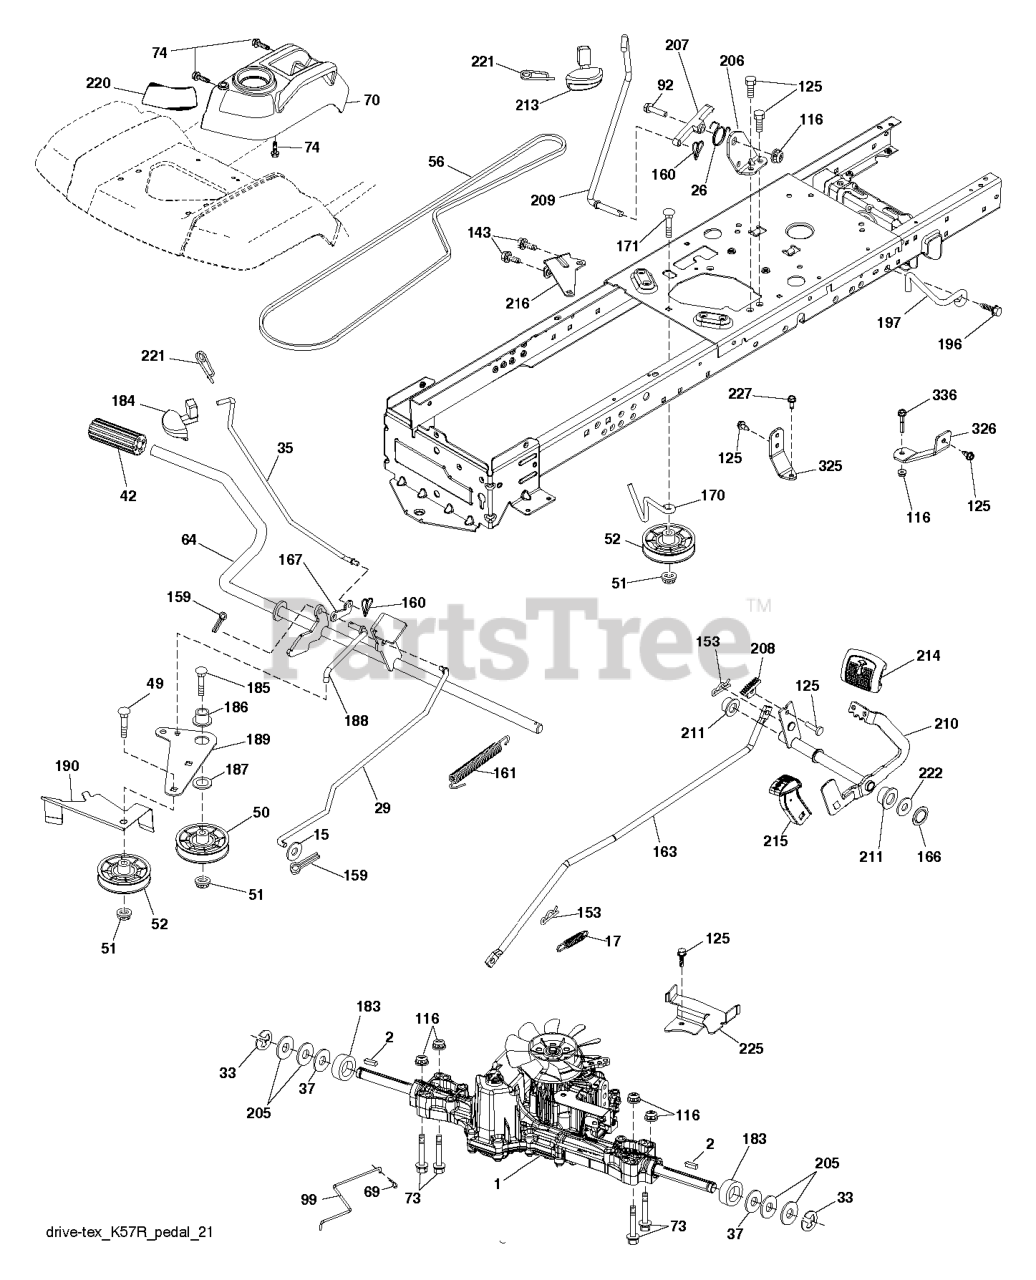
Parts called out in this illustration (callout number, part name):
2	SQUARE KEY
15	WASHER
17	SPRING.BRAKE.K46.GREEN
26	SPRING.RETURN.CRUISE
29	ROD.BRAKE.K46
35	ROD .BRAKE. PARKING. GT. HUSQ.
37	WASHER.HARDENED
42	PEDAL COVER T
50	IDLER.FLAT.910.OFFSET
51	NUT LOCK FLG 3/8-16 UNC
52	IDLER.V-GROOVE.910.OFFSET
56	V-BELT.MOWER.92.40.42/K46
64	SHAFT.ASM.PEDAL.BRK.CNTR
69	HAIRPIN.SOFT.ZINC.059X1.125
70	CONSOLE.ASM.RH.GT.FC.HUSQ
74	SCREW.HI-LO.CONSOLE
92	BOLT
99	ARM.PIVOTING.TCRD.GEN2.5.BAGGE
116	NUT LOCK HEX FLANGE 5/16-18
125	SCREW
143	SCR 5/16-18 X 1/2 SELFTAP ZN
153	RETAINER M
159	COTTER PIN
160	RETAINER CLIP
161	SPRING, RETURN LT
163	ROD.CONTROL.K57R.K46
166	NUT.PUSH.625
167	LATCH.BRAKE.SPRING
170	KEEPER.V-IDLER.CENTER.
183	SPACER AXLE
184	HANDLE.PARKING.BRAKE.H (BLK)
186	SPACER.RETAINER
187	WASHER 12/32X2X10GA
188	LINK.CLUTCH.GROUND DRIVE.LONG
189	BELLCRANK.GROUND.DRIVE.TEX.
190	KEEPER.BELLCRANK.DRIVE
196	SCREW 3/8-16X1
197	CLUTCH.ANTIROTATION.WIREFORM.
206	BRACKET.MOUNT.CRUISE.LATCH
207	LATCH.CONTROL.CRUISE.TEX
208	GEAR.SECTOR.CONTROL.CR
209	ROD.CONTROL.CRUISE.GT.
210	ROCKER.ASM.PEDAL.CONTR
211	BEARING.NYLON
213	KNOB.CONTROL.CRUSIE.HU
214	PEDAL.FORWARD.PAD.TEX
215	PEDAL.COVER.REVERSE.CRD.X428BK
216	BRACKET.PULLEY.IDLER.W/TEX
220	REFLECTOR.RH.TEX GT
221	RETAINER.SPRING.CLIP.H
222	WASHER 21/32 X 1-1/4 X 10 GA.
225	KEEPER.BELT.TRANSAXLE.K46
227	SCREW.THDROL.5/16-18X3/4.TTY
325	BRACKET.TRQ.STP.46.20".TIRE.LH
326	BRCKT.PNT.TRQ.STP.46.20TIRE.RH
336	BOLT.5/16-18X1-3/4.FLANGED.HEX
